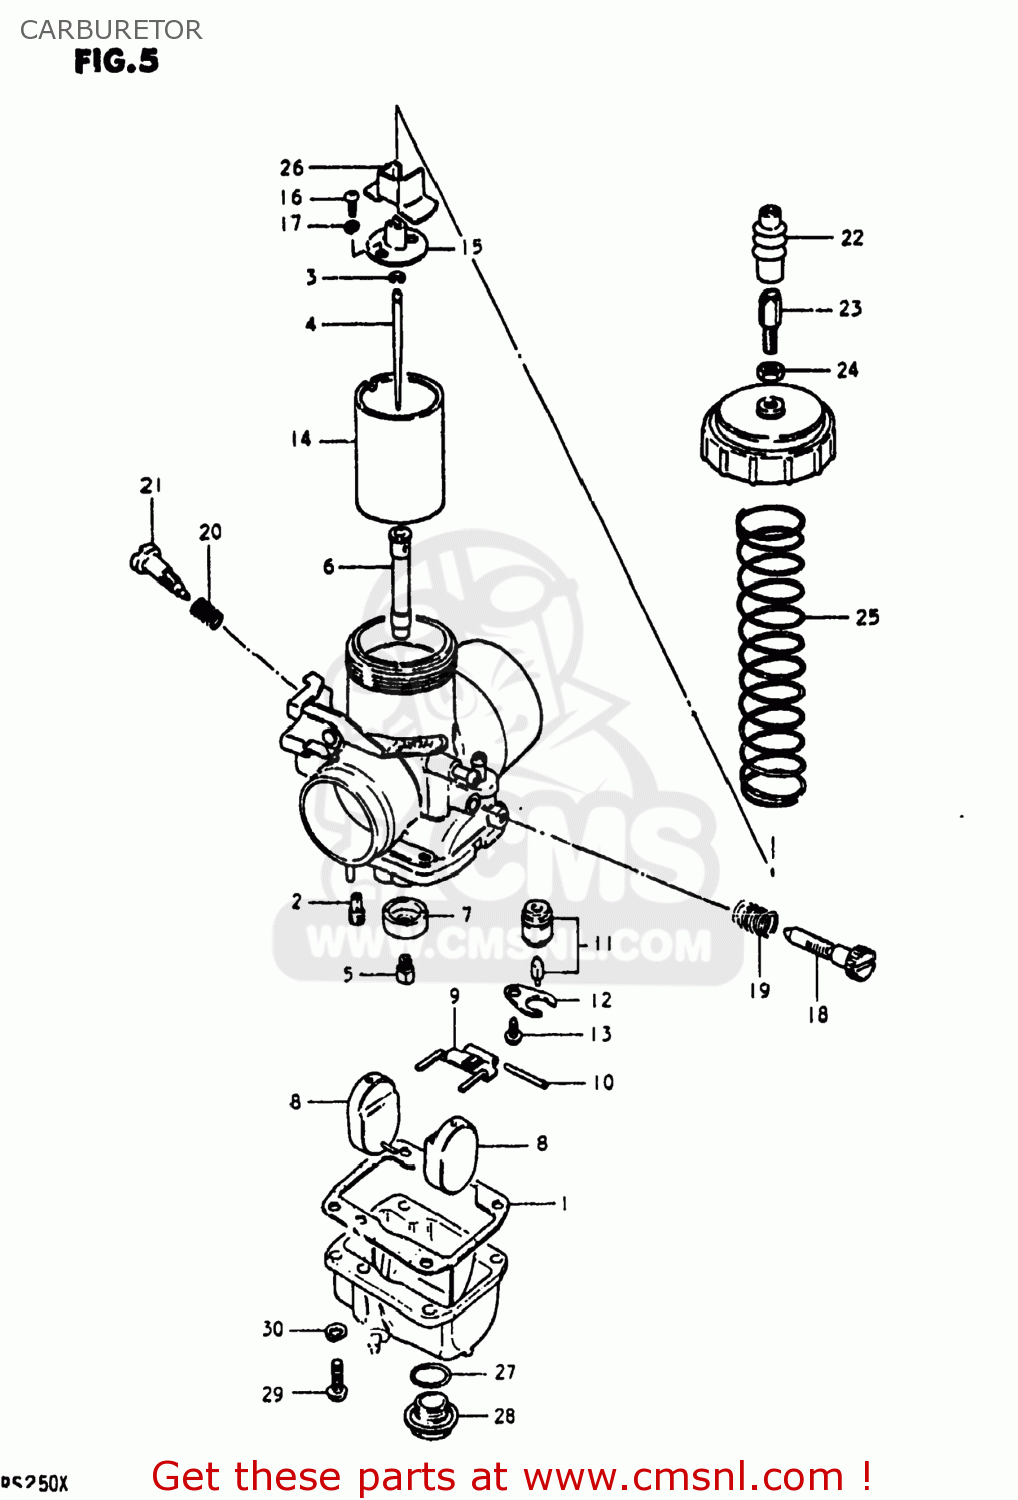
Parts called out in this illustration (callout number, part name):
1	GASKET,FLOAT CAHMBER (NAS)
2	JET,PILOT
3	CLIP
4	NEEDLE JET
5	JET
6	JET,NEEDLE
7	RING,MAIN JET FIXING
8	FLOAT
9	ARM,FLOAT
10	PIN,FLOAT
11	VALVE ASSEMBLY,NEEDLE
12	PLATE
13	SCREW
14	VALVE,THROTTLE
15	CONNECTOR
16	SCREW
17	LOCK WASHER
18	SCREW,THROTTLE STOP
19	SPRING,THROTTLE SCREW
20	SPRING
21	SCREW,PILOT AIR
22	CAP,CABLE ADJUSTER
23	ADJUSTER,CABLE
24	NUT
25	SPRING,THROTTLE VALVE RETURN
26	COVER,HOLDER
27	O-RING
28	PLUG
29	SCREW
30	LOCK WASHER
31	JET
